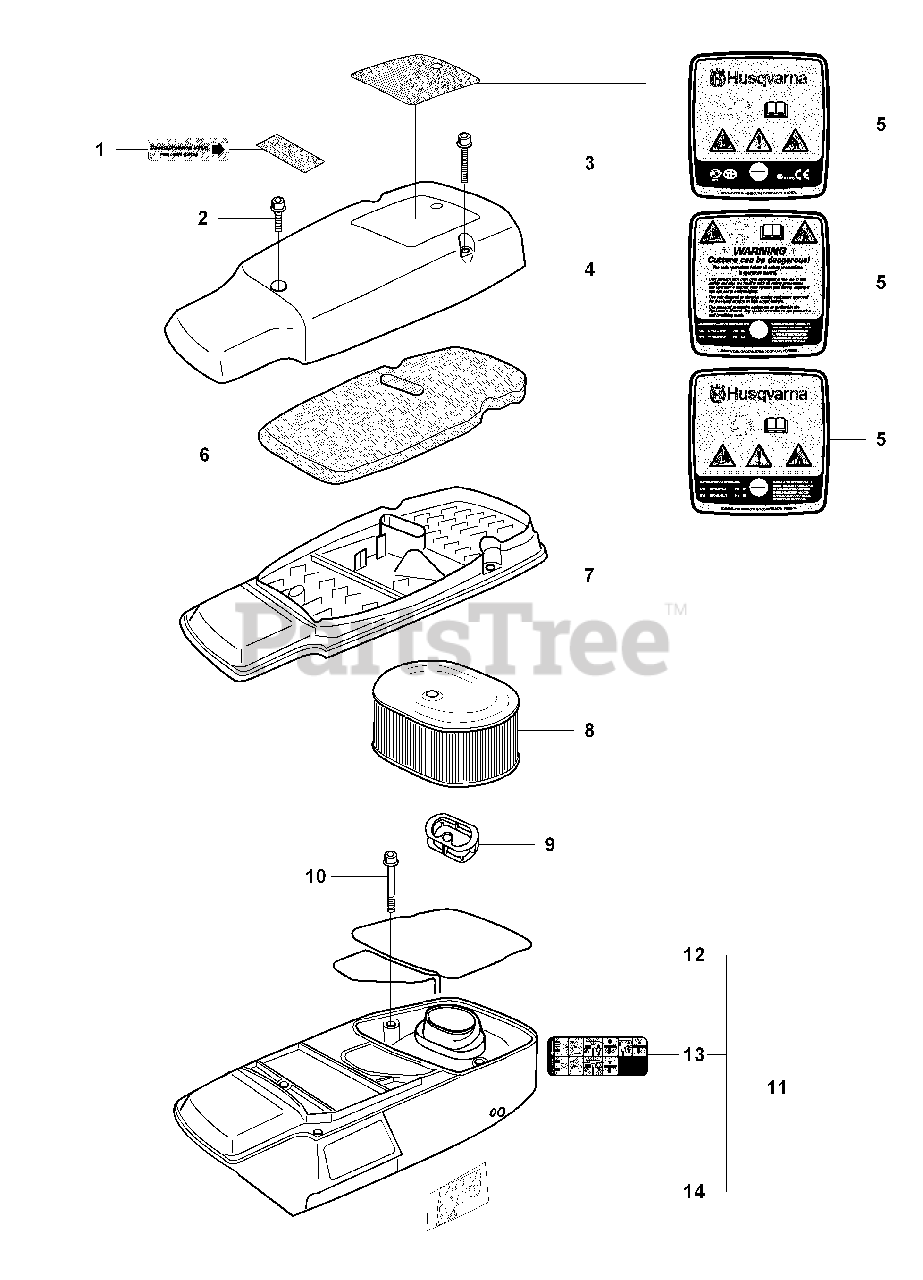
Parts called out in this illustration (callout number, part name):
2	SCREW
4	FILTER COVER
5	LABEL
7	FILTER BOTTOM
8	AIR FILTER
11	CYLINDER COVER
14	LABEL
